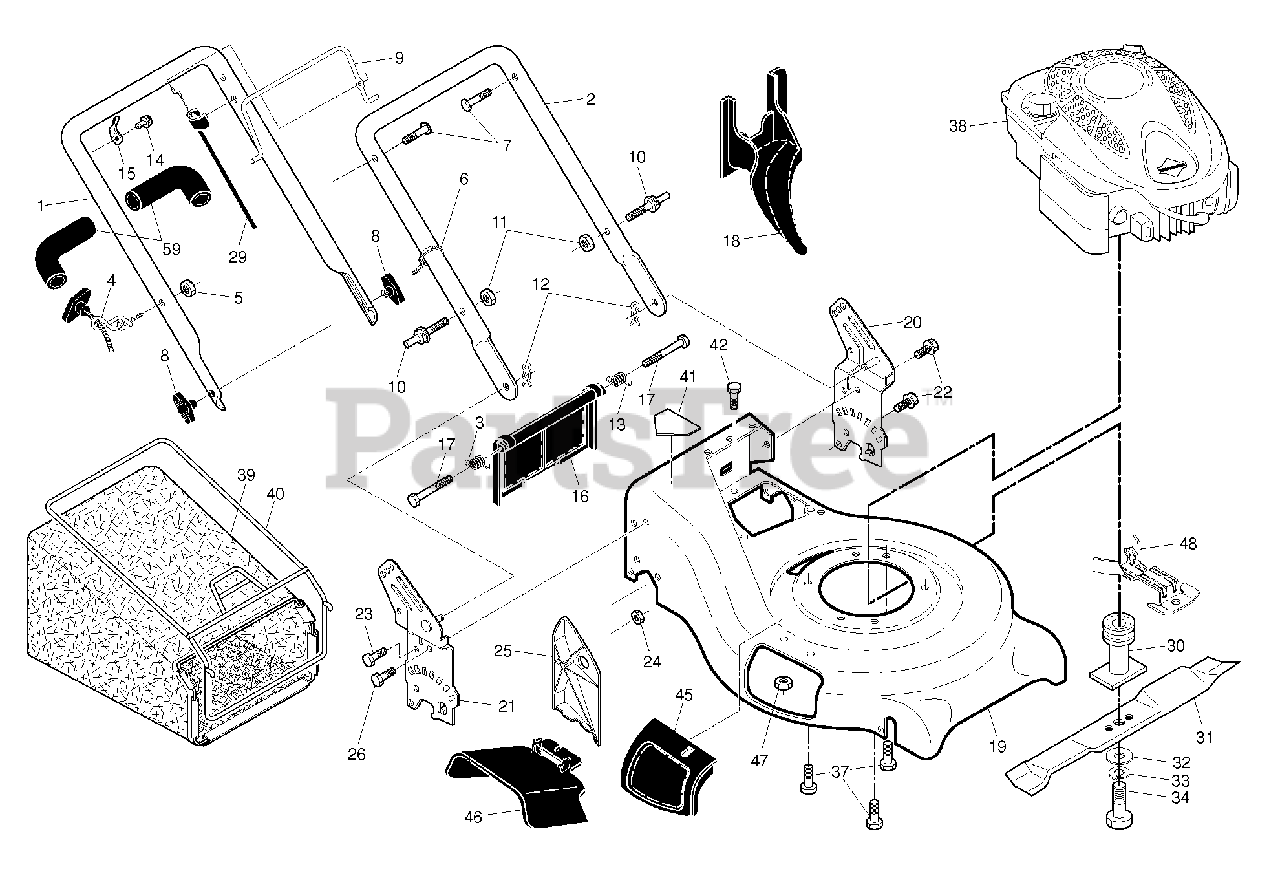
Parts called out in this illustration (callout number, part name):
2	HANDLE LOWER
3	SPRING.RH.REAR.DOOR.21.RWGD
4	GUIDE.ROPE.STD.BLK.ZIN
5	NUT
6	TIE GUIDE
7	BOLT, HANDLE 5/16-18X1.75
8	KNOB, DEFLECTOR
11	NUT, LOCK 5/16-18
12	HAIRPIN COTTER
13	SPRING.LH.REAR.DOOR.21.RWGD
15	BRACKET.UPSTOP.RT
16	REAR DOOR ASSEMBLY
18	PLUG.MULCHER.RGD.21.
20	BRKT.ASM HNDL
21	BRKT.ASM.HNDL
22	BOLT.HEX.HD.WASHER.5/16-18X.75
23	BOLT, HEX HEAD 5/16-18
24	NUT.71038.31-18.HEX.NYLOCK
25	CLIPPING DEFLECTOR
29	CABLE.MZR.47.75.SNAP-IN.PU.L
30	ADAPTER.BLADE/PULLEY.25M
31	BLADE.21.PUSH
32	WASHER,HARDEN
33	LOCKWASHER
34	SCREW, HEX HD 3/8-24 X 1-3/8
37	BOLT 3/8-16X1-1/8
40	FRAME.GBAG.21.RWGD.SC
41	DECAL.INTERNATIONL.CUTFINGER
42	SCREW 14-20 X 5/8
48	BRACKET.ENG/BELTKEEPER.BZP
59	GRIP.HANDLE.FOAM.WIDE.(1 SIDE)
